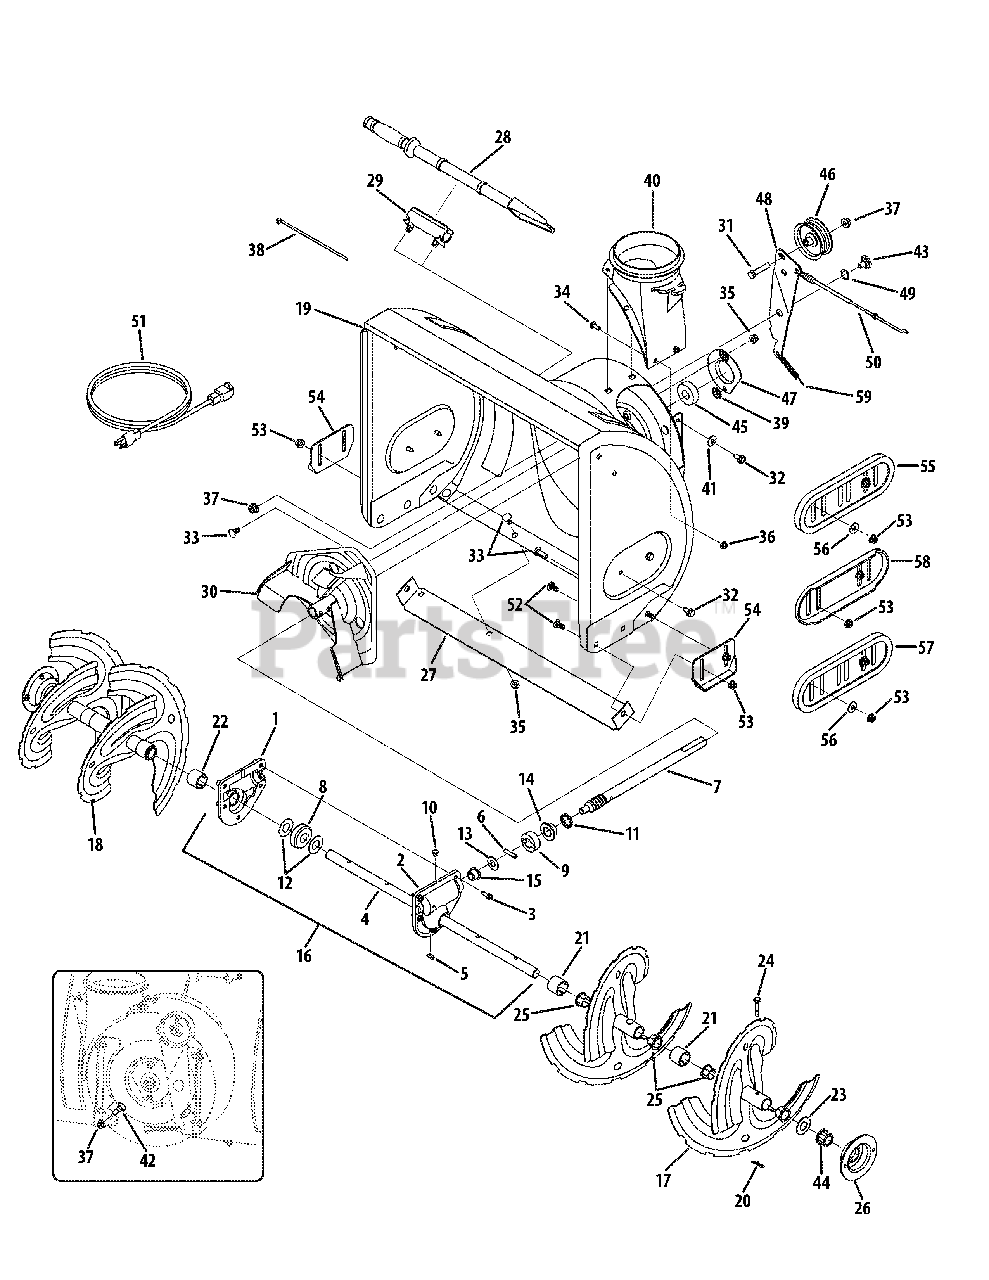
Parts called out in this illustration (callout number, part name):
1	Housing Assembly, RH
2	Housing Assembly, LH
3	Hex Washer Screw, 1/4-20 x .750
4	Auger Axle, 24"
4	Auger Axle, 26"
4	Auger Axle, 28"
5	Hi-Pro Key
6	Dowel Pin, .25 OD x 1.25 LG
7	Worm Shaft, .75 OD
8	Worm Gear 2OT, 24"
8	Worm Gear 2OT, 26"
8	Worm Gear 2OT, 28"& 30"
9	Thrust Collar, .756 ID x .600
10	Plug, 1/4 x .437
11	Oil Seal, .75 x 1.131 x .188
12	Flat Washer, .760 ID x 1.50 ID
13	Flat Washer, .51 x 1.12 x .06
14	Flng. Bearing, .75 ID x 1.00 OD x .59
15	Flange Bearing, .50 ID x .75 OD x .59
16	Gearbox Assembly, 24"
16	Gearbox Assembly, 26"
16	Gearbox Assembly, 28"
20	Bow-Tie Cotter Pin
21	Spacer, 1.2500 x .75 ID x 1.00 LG
22	Spacer, 1.250 x .75 ID x 3/16 LG
23	Flat Washer, .76 x 1.49 x .06
24	Shear Pin, .25 x 1.50
25	Flange Bushing, .800 ID x .910 OD
28	Chute Cleanout Tool
29	Cleanout Tool Mount
31	Hex Screw, 3/8 -16 x 1.75
32	Hex Washer Screw, 5/16-18 x .750
33	Carriage Bolt, 5/16-18 x .750
34	Carriage Screw, 1/4-20 x .75
35	Flange Lock Nut, 5/16-18
36	Flange Lock Nut, 1/4-20
37	Flange Lock Nut, 3/8 -16
38	Cable Tie, 3/16 x .05 x 7.4
39	Push Nut, .25 Dia.
40	Chute Adapter, 5"
41	Bell Washer, .340 x .872 x .060
42	Shoulder Bolt, .496 x .336 x 3/8 -16
43	Shoulder Screw, .625 x .17 x 3/8 -16
44	Hex Flange Bearing, .75 ID
45	Ball Bearing, .75 ID x 1.85 OD
46	Idler Pulley, .275 OD
47	Bearing Housing, 1.85 ID
49	Wave Washer, .625 x .885 x .015
50	Auger Drive Cable
51	Extension Cord
52	Carriage Bolt, 5/16-18 x .750
53	Flange Lock Nut, 5/16-18
54	Screw, Carriage 5/16-18 x .750
54	Nut, Nylon Lock 5/16-18
54	Washer, Flat .349 x .879 x .063
55	Skid Shoe, Polymer Small
55	Standard Polymer Reversible Shoe Kit
55	Screw, Carriage 5/16-18 x .750
55	Nut, Nylon Lock 5/16-18
55	Washer, Flat .349 x .879 x .063
56	Flat Washer, .349 x .879 x .063
57	Deluxe Polymer Skid Shoe
57	Deluxe Polymer Reversible Shoe Kit
57	Screw, Carriage 5/16-18 x .750
57	Nut, Nylon Lock 5/16-18
57	Washer, Flat .349 x .879 x .063
58	Screw, Carriage 5/16-18 x .750
58	Nut, Nylon Lock 5/16-18
58	Washer, Flat .349 x .879 x .063
59	Extension Spring
